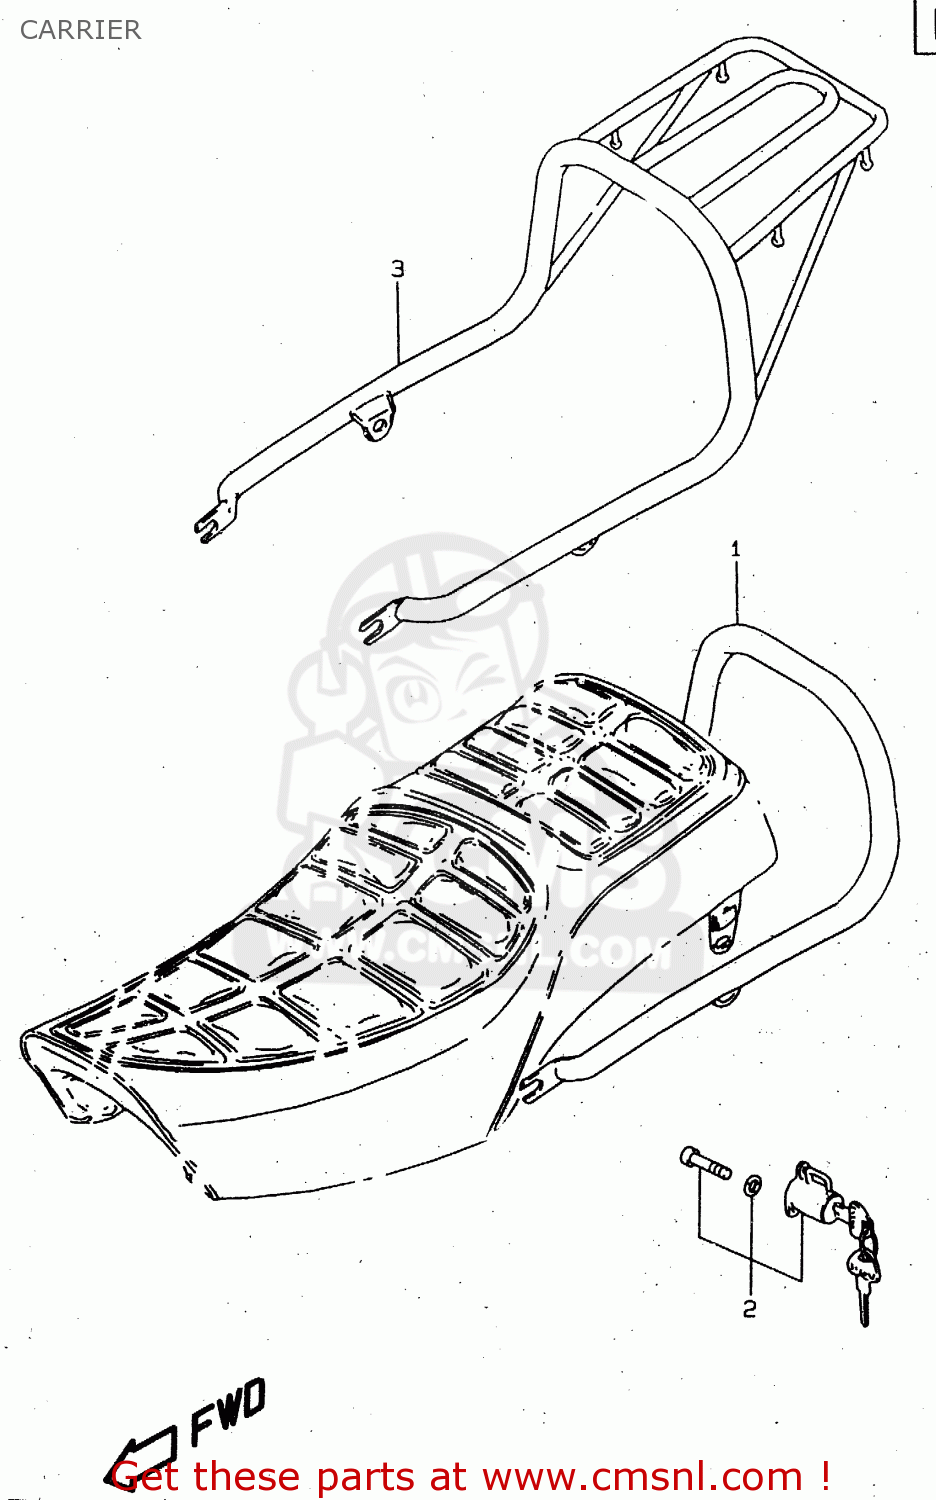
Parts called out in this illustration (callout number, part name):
1	HANDLE,PILLION RIDER
2	LOCK SET,HELMET
3	CARRIER,SPORT
